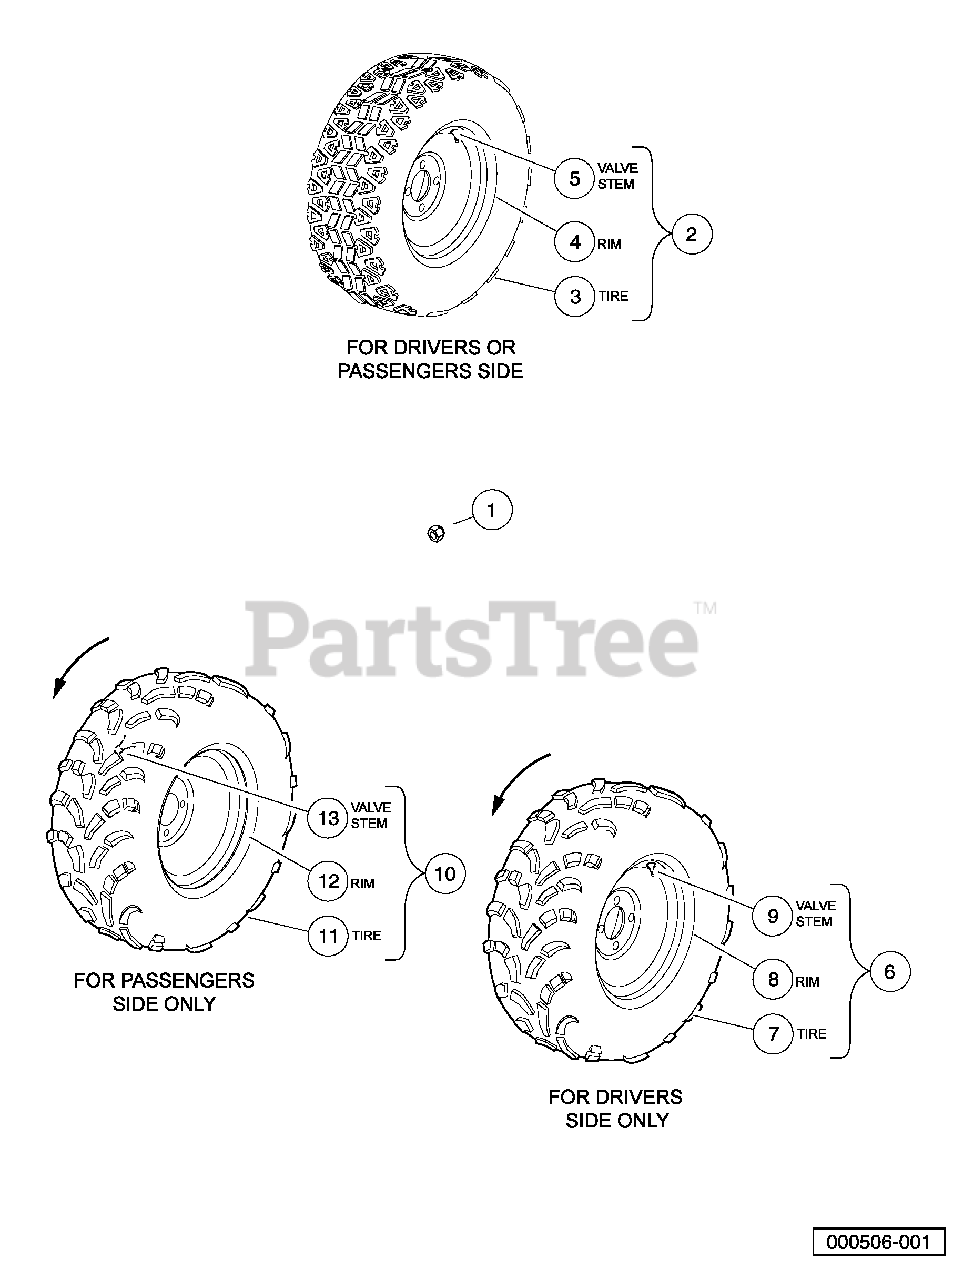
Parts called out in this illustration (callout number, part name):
1	Nut, Lug, 1/2-20 SAE J2283
2	Black Tire Asm HDAT 10.5 In
3	Heavy Duty All Terrain Tire, 25"
4	Wheel, All trail, 10 Win, Black
5	Valve Stem
6	Black Tire Asm Mud 11.0 In Left-Hand
7	Mud Tire, 25"
8	Wheel, All trail, 10 Win, Black
9	Valve Stem
10	Black Tire Asm Mud 11.0 In Right-Hand
11	Mud Tire, 25"
12	Wheel, All trail, 10 Win, Black
13	Valve Stem
